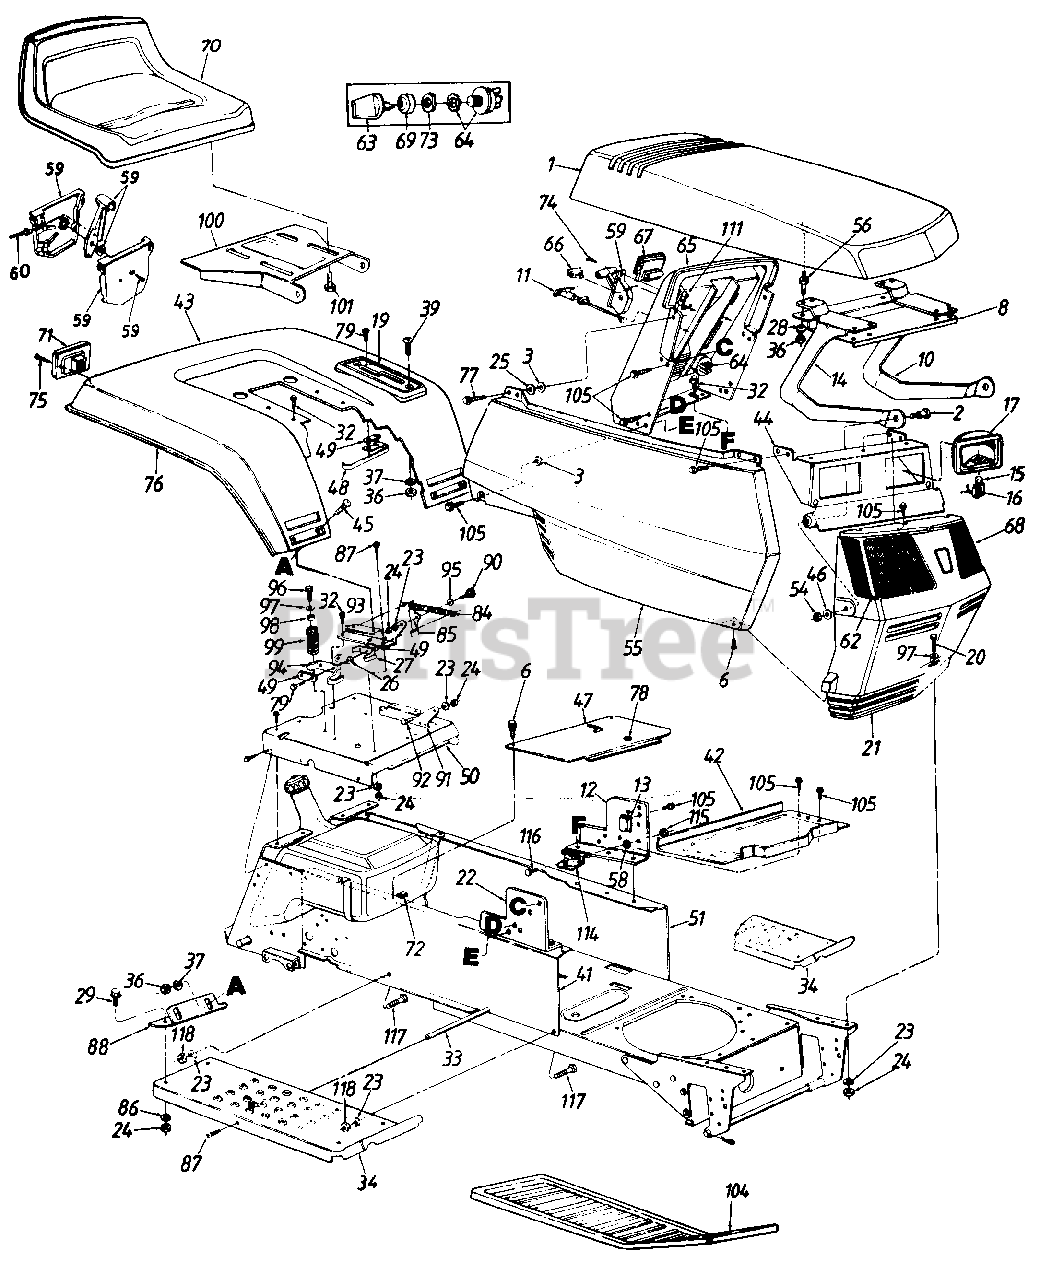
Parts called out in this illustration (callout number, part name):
3	Bolt Retainer 1/4" I.D.
6	Truss Mach. B-Tap Scr. #10 x .5" Lg.
8	Hood Reinforcement
10	Hood Hinge L.H.
11	Choke Control
12	Dash Support Brkt. L.H.
13	Circuit Breaker
14	Hood Hinge R.H.
15	Lamp
16	Twist Lock Lamp Socket
17	Headlight Housing
19	Speed Control Index Brkt.
20	Hex Bolt 5/16-18 x .75" Lg.
23	L-Wash. 5/16" I.D.
24	Hex Nut 5/16-18 Thd.
25	Fl-Wash. 1/4" I.D. x .93" O.D.
26	Insulator Center Plate
27	Seat Spring Switch
28	Bell-Wash. .265" I.D. x .75"
29	Hex Bolt 5/16-18 x 1.0" Lg.
32	Hex Wash. Hd. AB-Tap Scr. 5/16 x .75" Lg.
33	Running Board Rod
37	L-Wash. 1/4" I.D.
39	Truss Mach. Scr. 1/4-20 x 1.0" Lg.
41	R.H. Side Frame
42	Battery Plate
46	Fl-Wash. .328" I.D. x .68" O.D.
47	Transmission Panel
48	Reverse Safety Switch
49	Insulator End Plate
50	Seat Plate
51	L.H. Side Frame
54	Hex Cent. L-Nut 5/16-18 Thd.
55	Side Cover R.H.
56	Double Ended Stud 1/4-20 Thd.
58	Ext. L-Wash. 1/4" I.D.
59	Throttle Control Box Ass'y.
60	Throttle Control Wire 35" Lg.
62	Lens R.H.
63	Ignition Key
64	Ignition Switch
65	Dash Panel
66	Light Switch
67	Ammeter
68	Lens L.H.
69	Ignition Switch Cap
70	Seat Ass'y.
71	Taillight Ass'y.
72	Speed Nut #10Z
73	Ignition Switch Nut
74	Truss Mach. AB-Tap Scr. #10 x .5" Lg.
75	Truss Hd. AB-Tap Scr. #6 x .62" Lg.
76	Trim Strip 81"
77	Hex Wash. Hd. Tap Scr. 1/4 x .75" Lg.
78	Snap Bushing
79	Hex Wash. Hd. AB-Tap Scr. #8 x .50" Lg.
84	Ext. Spring 5.31" Lg.
85	Seat Lift Brkt.
86	Bell-Wash. .345" I.D. x .88" O.D.
87	Truss Machine Scr. 5/16-18 x .75" Lg.
95	Spr.-Wash..445" I.D.
96	Hex Wash. Hd. Tap Scr. 5/16-18 x .75" Lg.
97	Fl-Wash. .344" I.D.
98	Bushing
99	Compression Spring
100	Seat Pivot Bracket
101	Hex Tap Scr. 3/8-16 x .75"
104	Foot Pad
105	Hex Tap Scr. 1/4-20 x .5" Lg.
111	Speed Nut 1/4-20 Thd.
114	Solenoid
115	Hex Sems Nut 1/4-20 Thd.
116	Hex Bolt 1/4-20 x .5" Lg.
117	Rib Neck Bolt 5/16-24 x .75" Lg.
118	Hex Nut 5/16-24 Thd.
